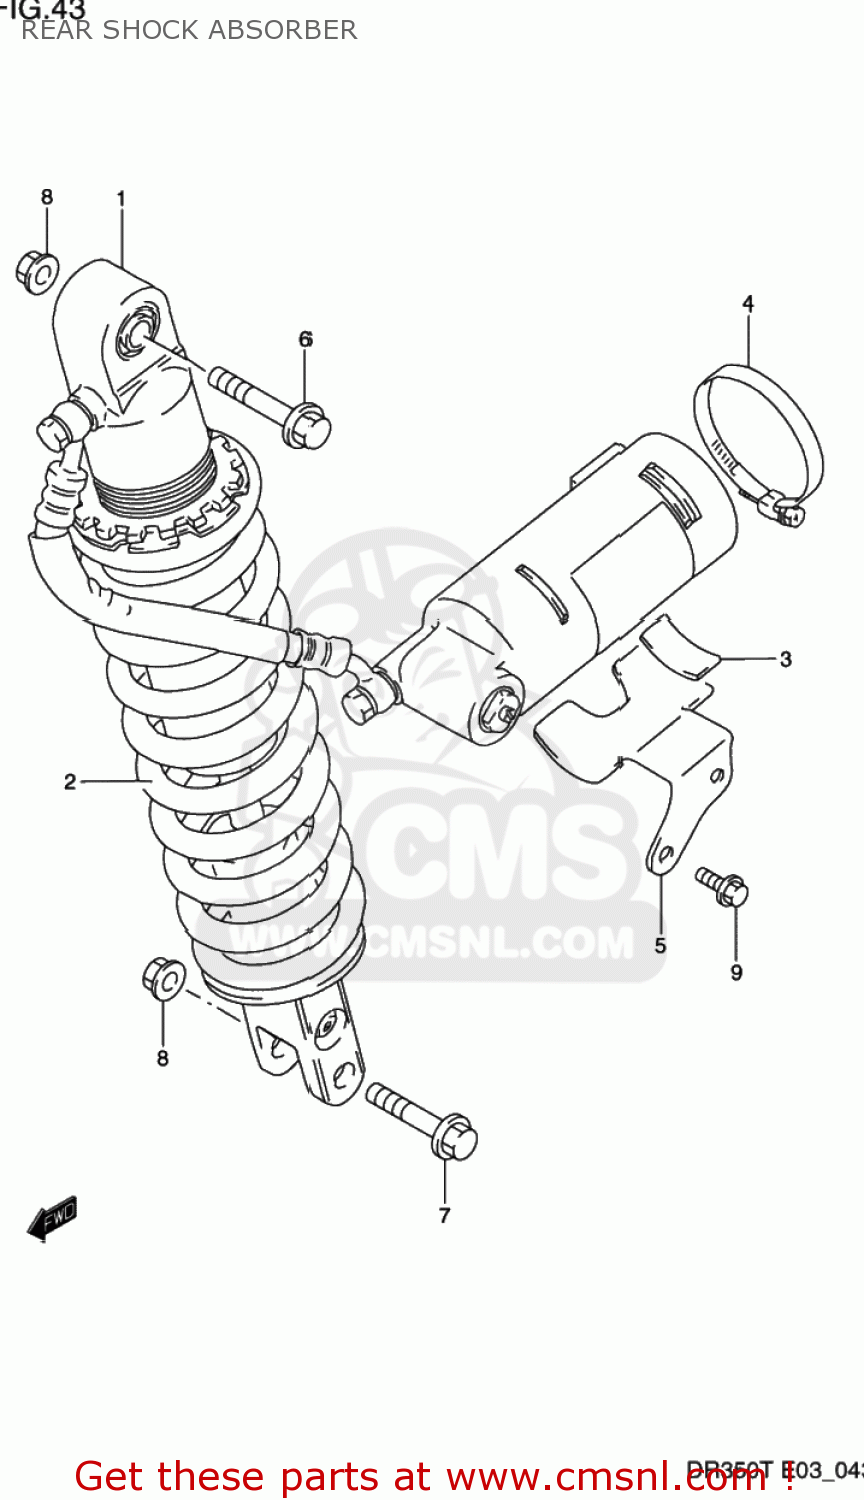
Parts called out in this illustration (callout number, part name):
1	ABSORBER ASSEMBLY,REAR SHOCK
2	SPRING
3	CUSHION
4	CLAMP
5	BRACKET,RESERVOIR TANK
6	BOLT,REAR SHOCK ABSORBER
7	BOLT,REAR SHOCK ABSORBER
8	NUT
9	BOLT
